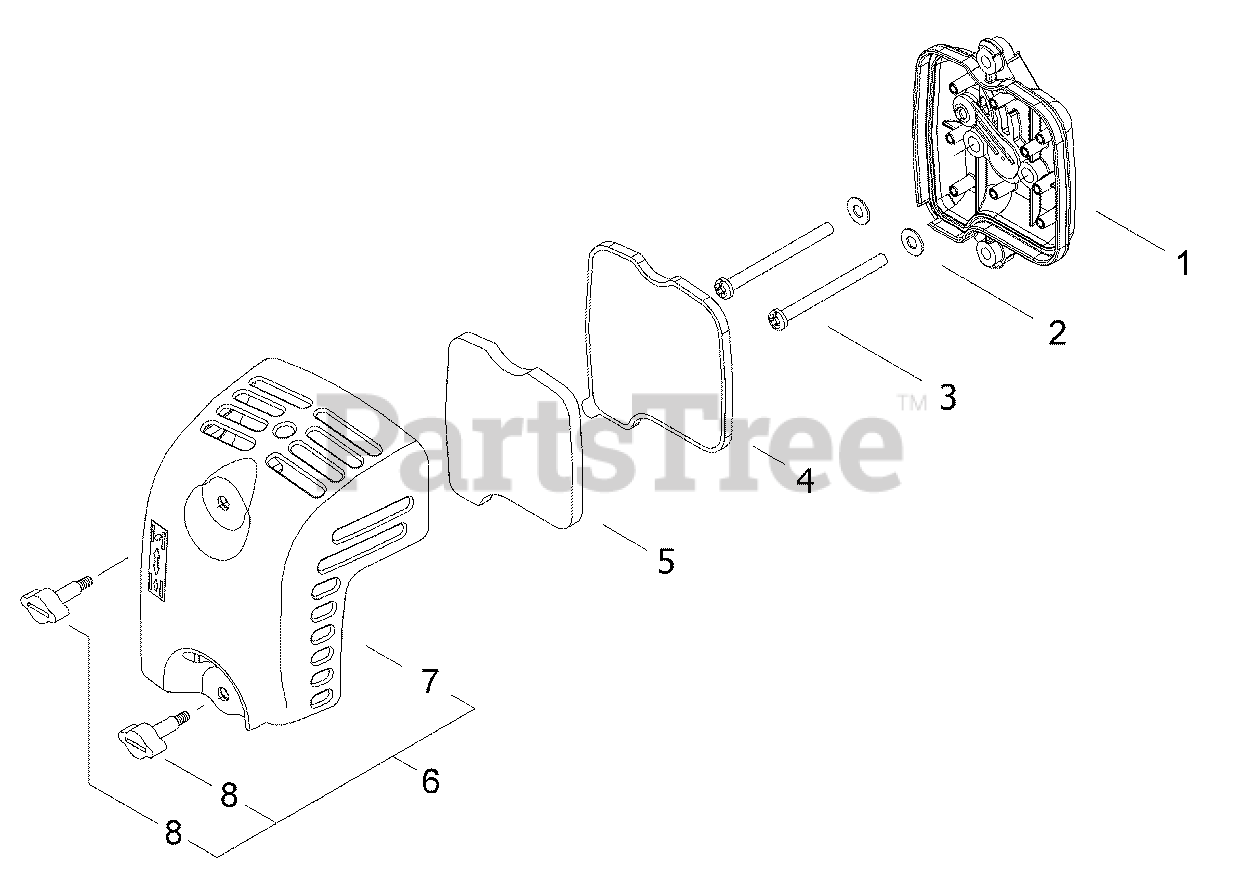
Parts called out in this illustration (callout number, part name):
1	AIR FILTER CASE ASSY
2	WASHER - 5
3	SCREW - 5X60
4	FILTER, AIR
5	PRE-FILTER - FOAM
6	AIR FILTER COVER ASSY
7	COVER, AIR FILTER
8	THUMBSCREW
